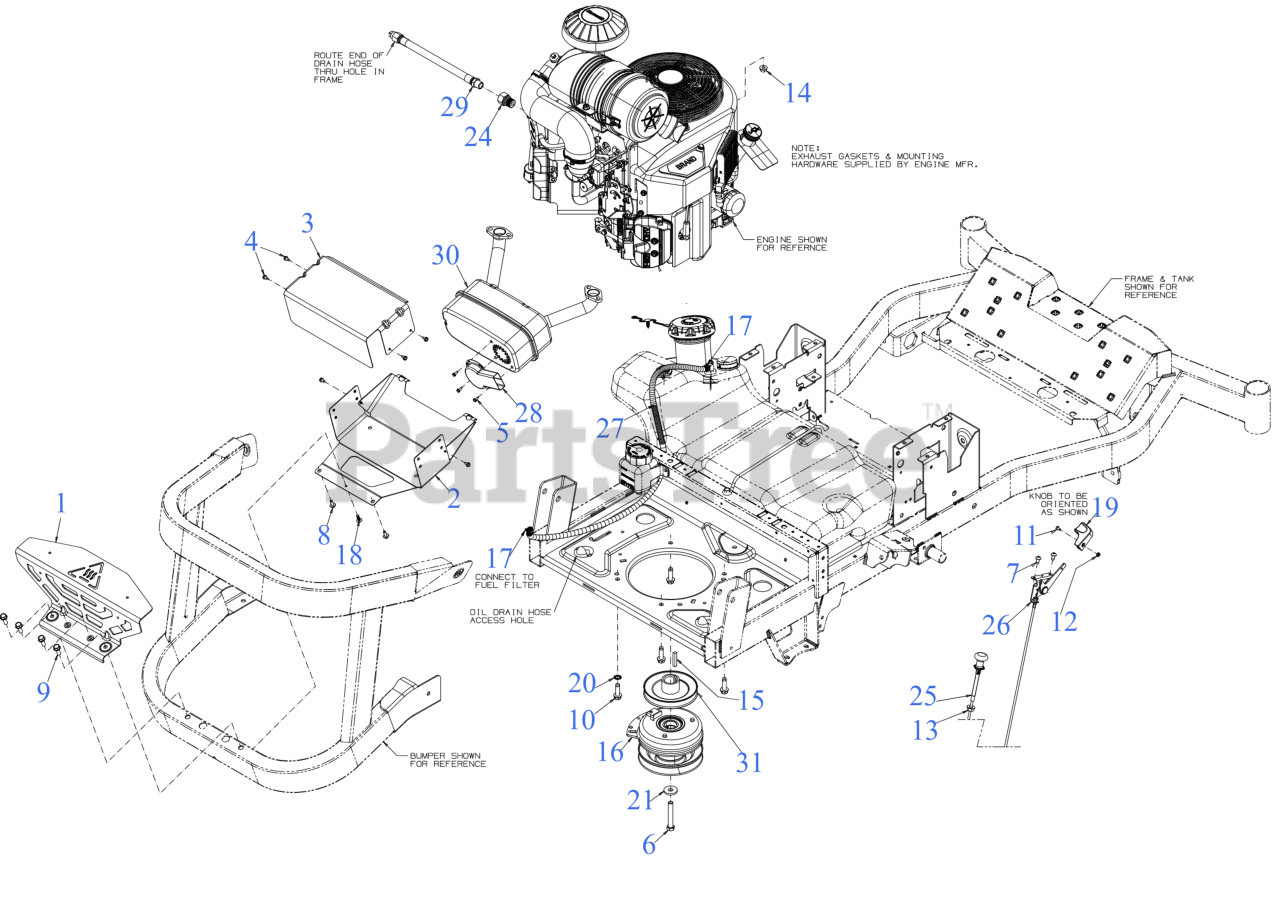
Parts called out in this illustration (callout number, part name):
1	MUFFLER COVER (REAR) (BLACK)
2	MUFFLER SHIELD (LOWER)
3	MUFFLER SHIELD (TOP)
4	HEX SCREW AB-TAP #10 x .50
5	HEX SCREW WASHER HD #8-18 x 0.500
6	SCREW 7/16-20:2.75 GR5
7	SCREW 1/4-20 x .5
8	SCREW M6-1 x .625
9	SCREW 5/16-18 x .875 GR5
10	SCREW 3/8-16 X1.250
11	SCREW #8-32X.38 LG
12	HEX NUT 8-32
13	HEX FLANGE NUT
14	HEX FLANGE NUT M8X
15	SQUARE KEY 1/4 x 1.50
16	ELECTRIC PTO CLUTCH
17	HOSE CLAMP 1/20
18	RATCHET CLIP (.188 x .85)
19	THROTTLE CONTROL KNOB
20	LOCK WASHER 3/8
21	FLAT WASHER .445 x 1.248 x .170
24	OIL DRAIN FITTING (M20x2.5)
25	CHOKE CABLE 40.5 LG
26	THROTTLE CABLE 38.5"
27	FUEL HOSE LOW PERMEATION 36"
28	EXHAUST DELECTOR (LONG)
29	OIL DRAIN HOSE (11.26" 3/8 NPT)
30	EXHAUST MUFFLER (KAW TWN)
31	TRANSMISSION DRIVE PULLEY
